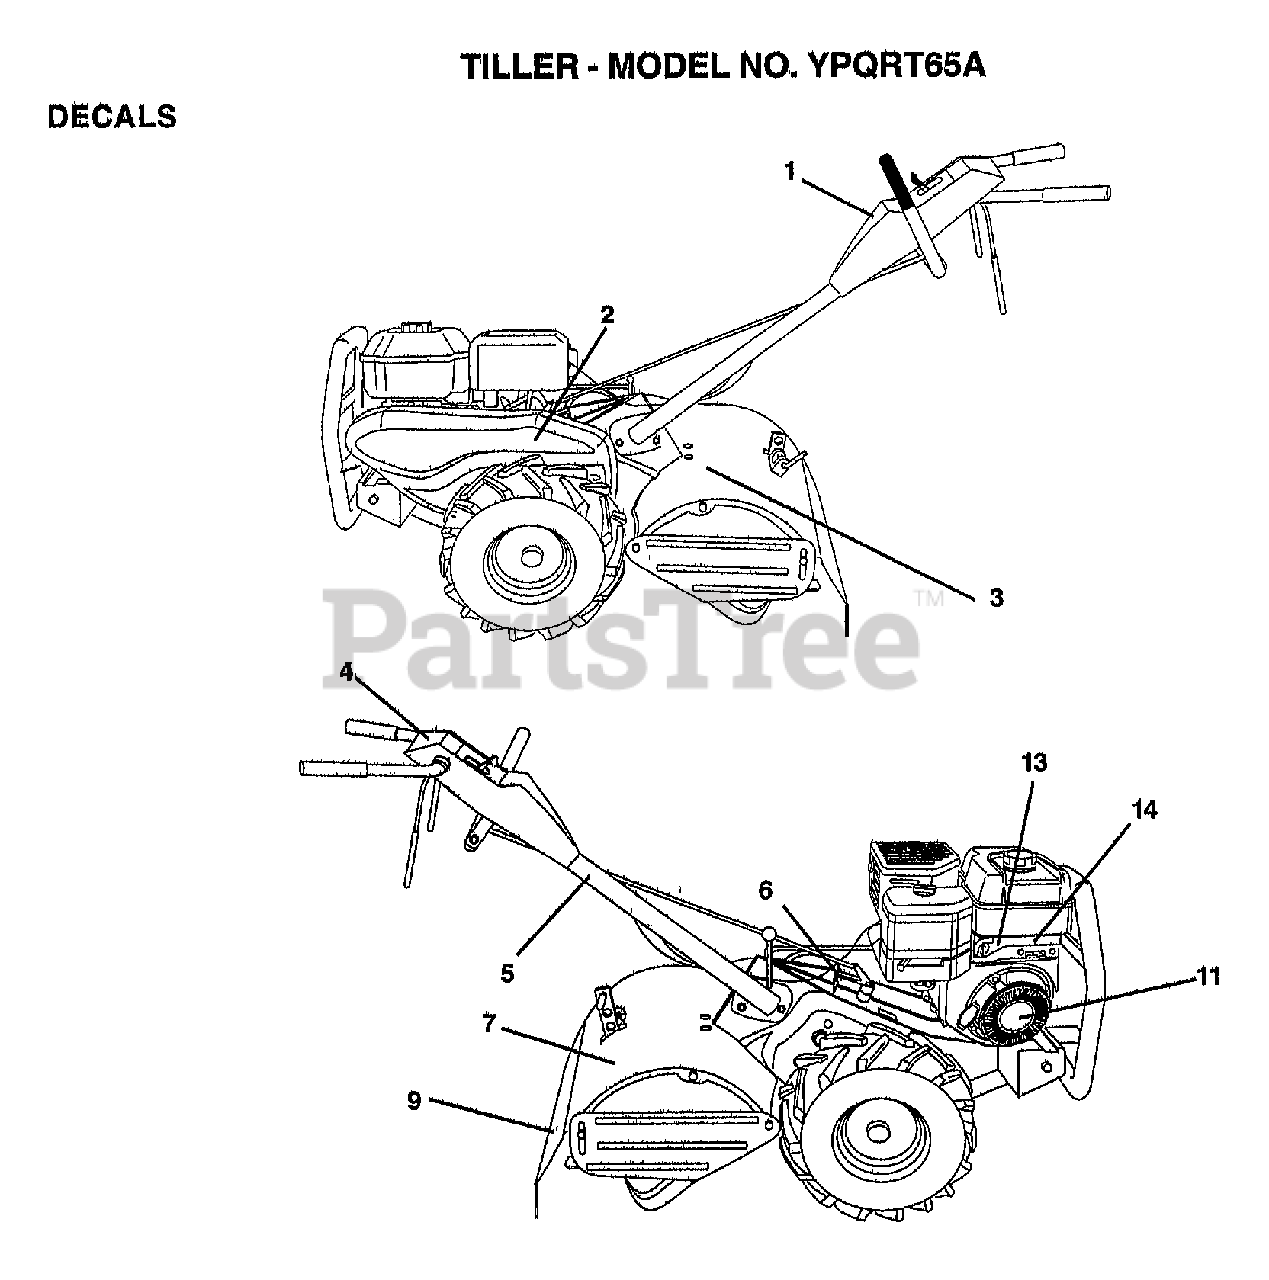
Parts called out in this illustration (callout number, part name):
1	DECAL PANEL CNTRL
2	DECAL, LOGO BELT GUARD
3	DECAL SHIELD TINE
4	DECAL.INSTRUCTION
5	DECAL TI
6	DECAL CRT
7	DECAL.CAUTION
13	DECAL, CHOKE
